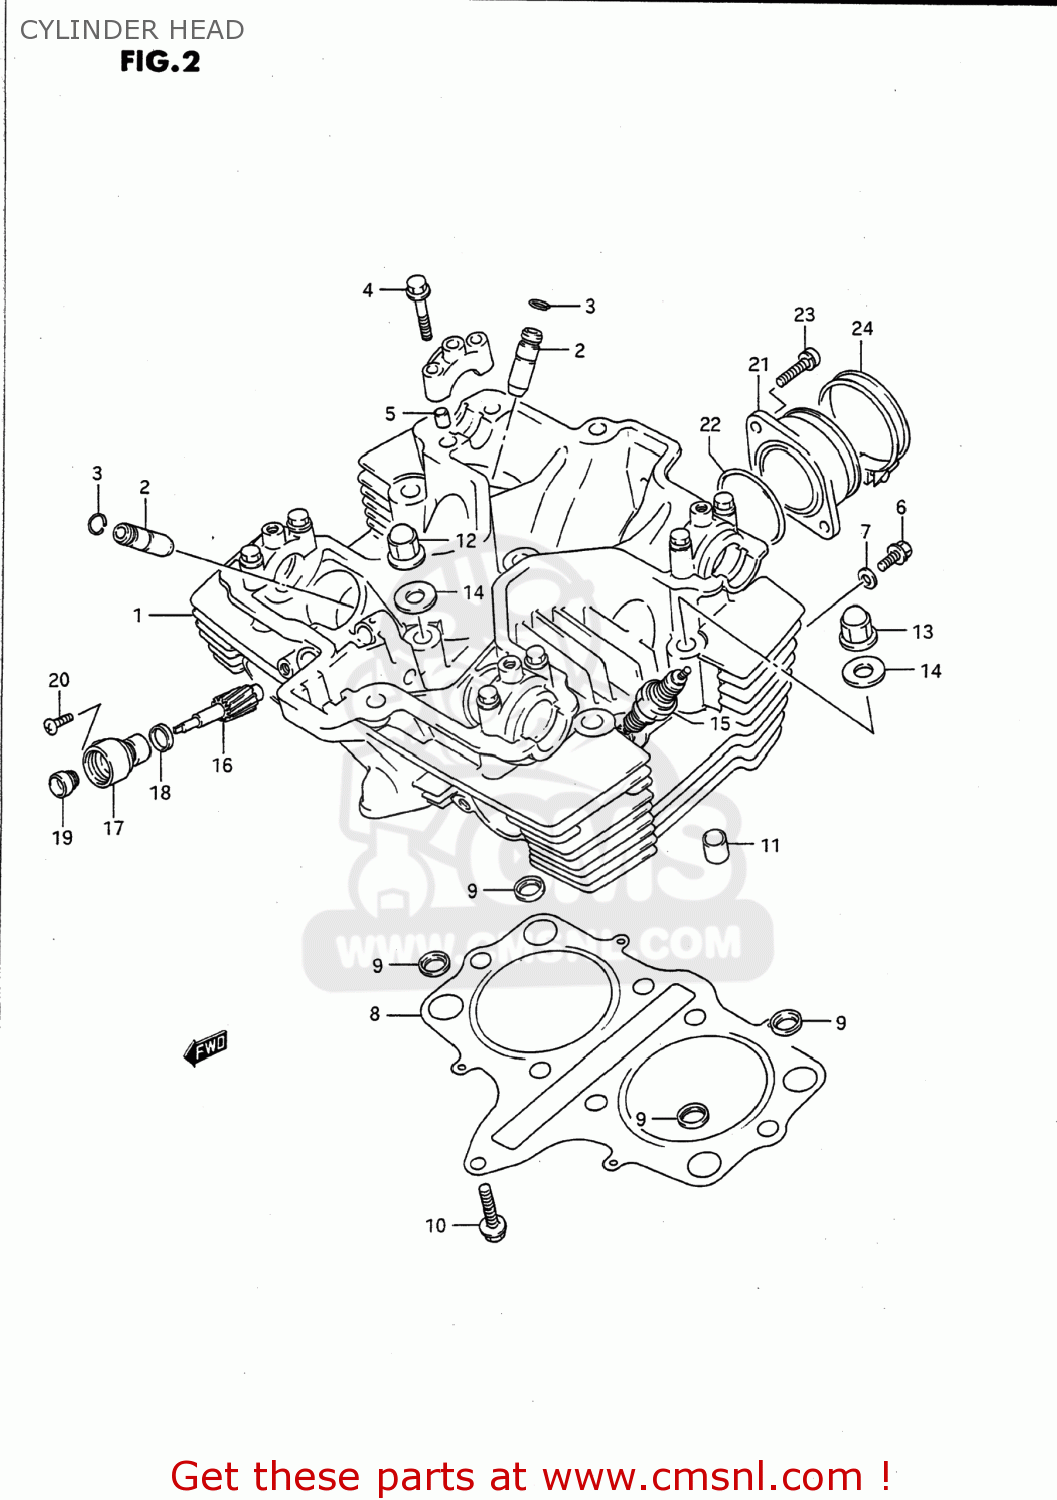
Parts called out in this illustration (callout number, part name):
1	HEAD ASSEMBLY,CYLINDER
2	GUIDE,INTAKE VALVE
3	RING,SNAP
4	BOLT(6X39)
5	PIN(6.2X8X11)
6	BOLT
7	GASKET(5.8X13X1.2) (NAS)
8	GASKET,CYLINDER HEAD (NAS)
9	O RING,HEAD GASKET
10	BOLT
11	PIN
12	NUT
13	NUT
14	GASKET(10.5X22X2) (NAS)
15	PLUG,SPARK(DPR8EA-9)
16	GEAR,TACHOMETER DRIVEN
17	SLEEVE,TACHOMETER DRIVE GEAR
18	SEAL,TACHOMETER DRIVEN
19	SEAL,OIL(5X12X8)
20	SCREW(5X12)
21	PIPE COMP,INTAKE
22	O-RING (D:2.4 ID:39.7)
23	SCREW
24	CLAMP
